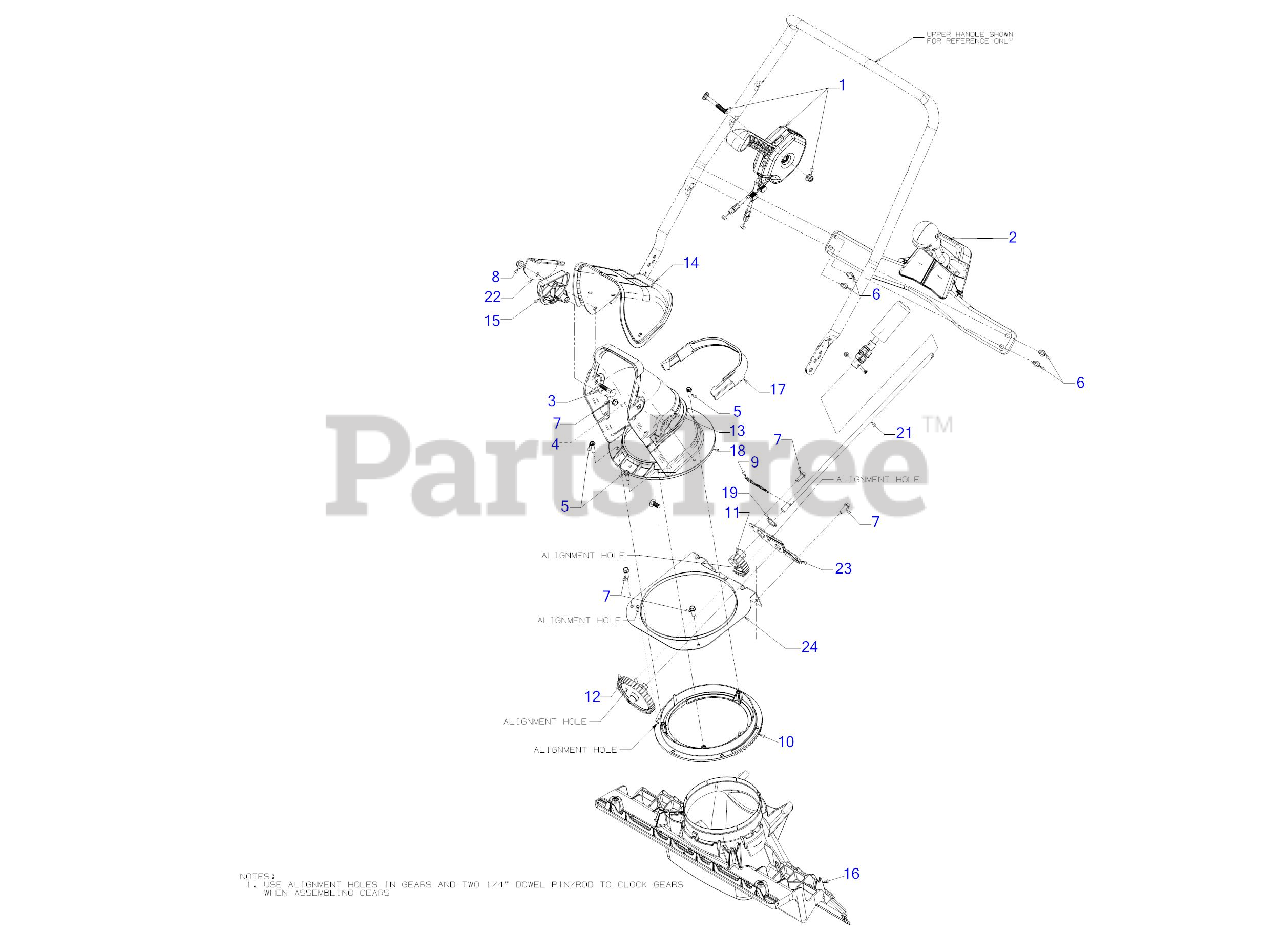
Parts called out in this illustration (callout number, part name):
1	See Chute Tilt Control Breakdown
2	CHUTE ROTATION HANDLE ASSEMBLY
3	CARRIAGE BOLT 5/16-18 x 1.50
4	CARRIAGE BOLT 5/16-18 x .75
5	SCREW 1/4 x .750
6	SCREW 1/4-20 X.500
7	SCREW 1/4-15 x .750
8	FLANGE LOCK NUT 5/16-18
9	COTTER PIN .125X2.
10	BEVEL GEAR 95T
11	SPUR GEAR
12	SPUR-GEAR 40T
13	WING KNOB 5/16-18
14	UPPER CHUTE
15	CABLE CHUTE GUIDE
16	CHUTE ADAPTER
17	CHUTE PLUG
18	LOWER CHUTE 6.5
19	FLAT WASHER .750X1.000X.060:HD
21	LOWER CHUTE CRANK ROD
22	CABLE BRACKET
23	GEAR PLATE
24	RETAIN GEAR BRACKET
